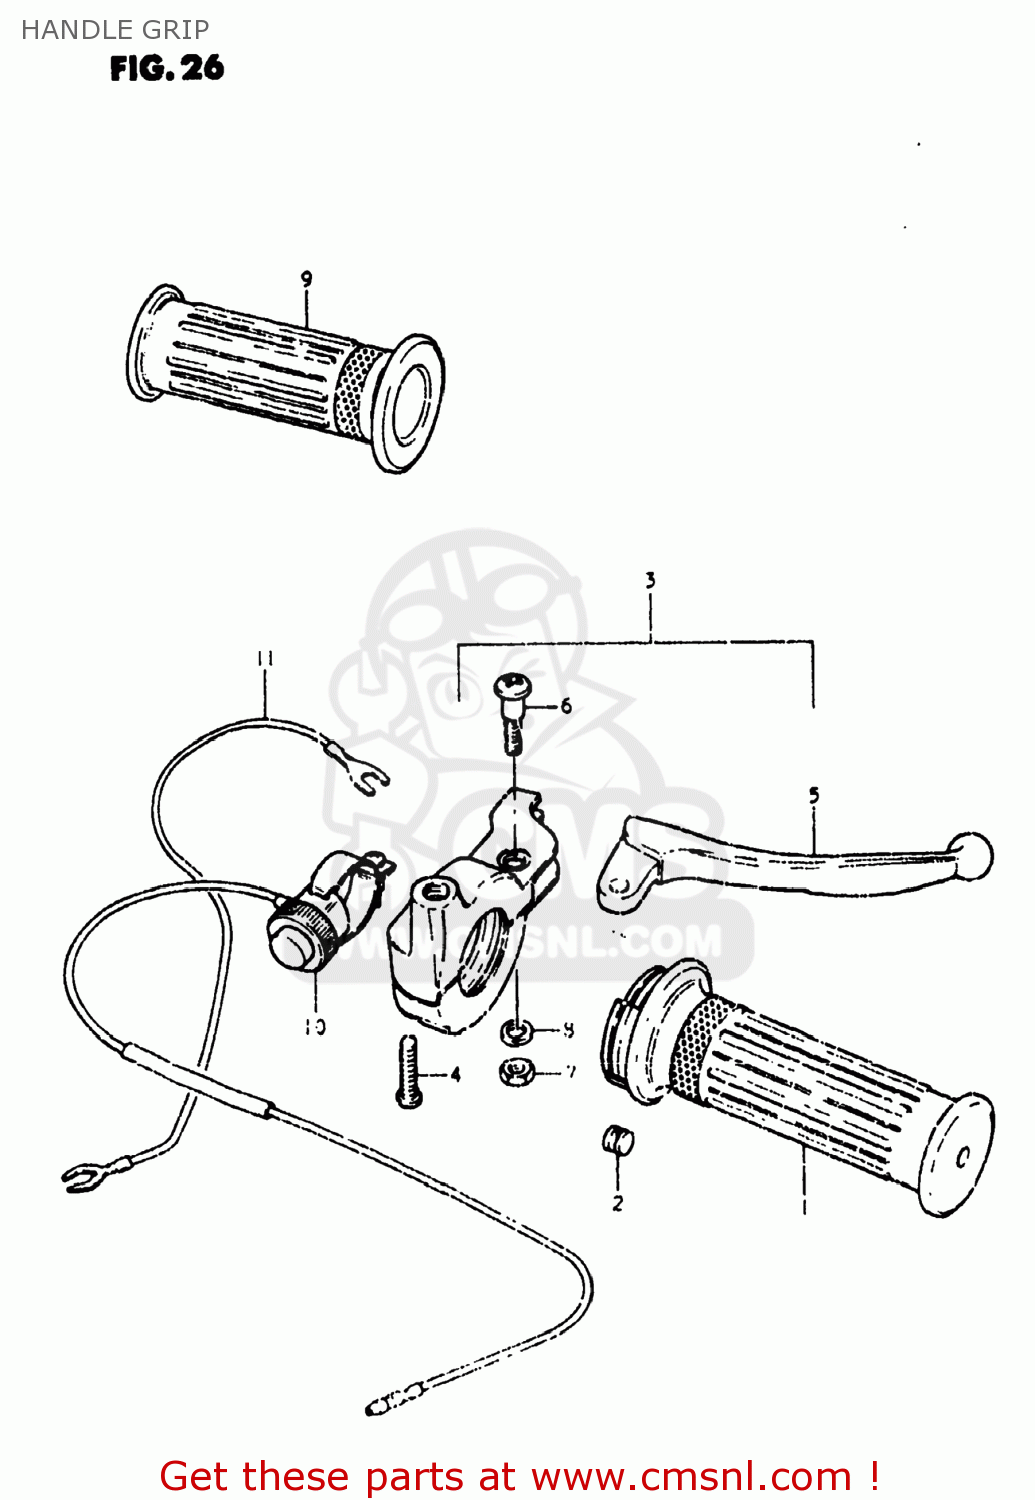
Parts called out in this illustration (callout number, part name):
1	GRIP,THROTTLE
2	PIECE,THROTTLE END
3	LEVER ASSY,BRAKE
4	SCREW
5	LEVER,BRAKE
6	SCREW
7	NUT
8	LOCK WASHER
9	GRIP,L
10	SWITCH ASSEMBLY
11	WIRE
